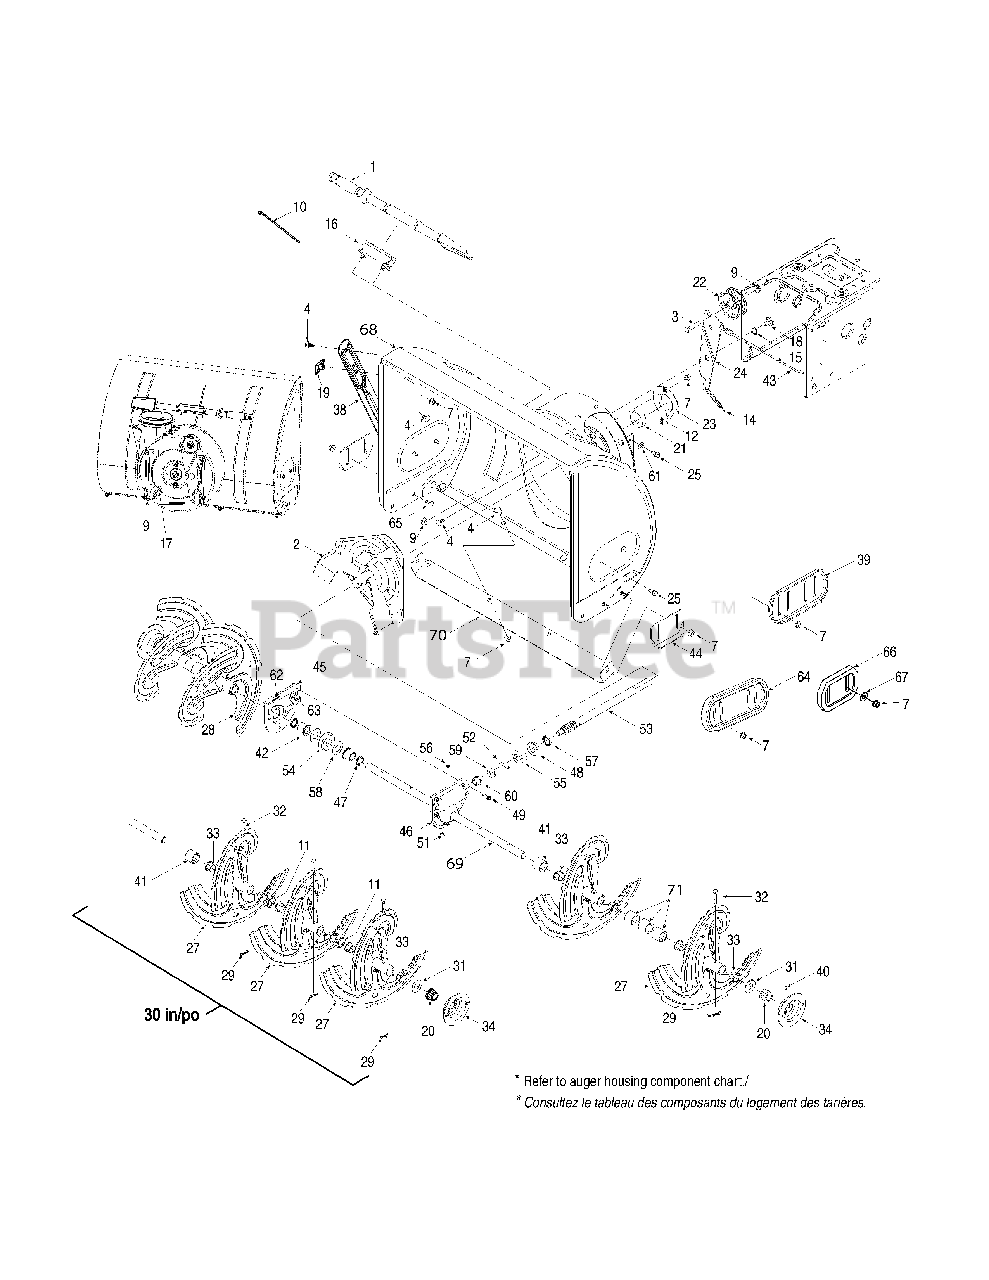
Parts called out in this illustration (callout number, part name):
1	Clean-Out Tool
2	Impeller Ass'y 12 po
3	Hex Screw 3/8-16 x 1.75
4	Carriage Bolt 5/16-18 x .75
7	Flange Locknut 5/16-18 Gr. F Nylon
9	Hex L-Flanged Nut 3/8-16 Gr. F Nylon
11	Spacer 1.25 x .75 x 3/16" Lg.
12	Push-on Nut .25 dia.
14	Extension Spring .38 OD x 4.59" Lg.
15	Wave Washer .660 ID x .88 OD x .010
16	Cleanout Tool Mount
17	Shld. Screw .500 Dia. x .335" Lg.
18	Shoulder Scr .625 Dia x .170
20	Hex. Flange Brg. .751" I.D.
21	Self-align ing Bearing
22	Flat Idler Pulley 2.75" OD
23	Bearing Housing 1.85 ID
24	Auger Idler Brake Bracket
25	Hex TT Screw 3/8-16 x .75
27	Spiral Ass'y LH
28	Spiral Ass'y RH
29	Bow Tie Cotter Pin
31	Flat Washer .760 ID x 1.49 OD
32	Shear Pin .25 x 1.5 Gr. 2
33	Flange Bushing
38	Drift Cutter - Optional
39	Reversible Slide Shoe (steel)
40	Grease Fitting (Optional)
41	Spacer 1.25 x .75 x 1.00
42	Flange Bearing.75 ID x 1.0 OD x .975
43	Auger Clutch Cable
45	RH Reduced Auger Housing
46	LH Reduced Auger Housing
47	Oil Seal .75 x 1.0 x .125
48	Flange Bearing .75 ID x 1.00 OD x .50
49	Thd Forming Screw 1/4-20 x .75
51	Hi Pro Key 3/16 x 5/8
52	Dowel Pin .25 OD x 1.2
53	Worm Shaft .75 OD
54	Worm Gear 20T (22", 24" & 26")
55	Thrust Collar
56	Plug, 1/4 x .437
57	Oil Seal .75 x 1 x .131
58	Flat Washer .76 ID x 1.5 OD x .03
59	Fl. Washer .510 x 1.120 x .060
60	Flange Bearing .75 ID x 1.0 OD x .925
61	Cupped Washer .345 ID x .88 OD x .060
62	Loctite Seal ant 5699
63	Grease - Alvania EP Lead Free
64	Reversible Slide Shoe (plastic)
65	Carriage Bolt 5/16-18 x .75 (w/steel slide shoes)
66	Small Reversible Slide Shoe (plastic)
67	Flat Washer .349 ID x .879 OD x .063
68	Auger Housing
69	Auger Axle
69	Gear Box Ass'y
70	Shave Plate
